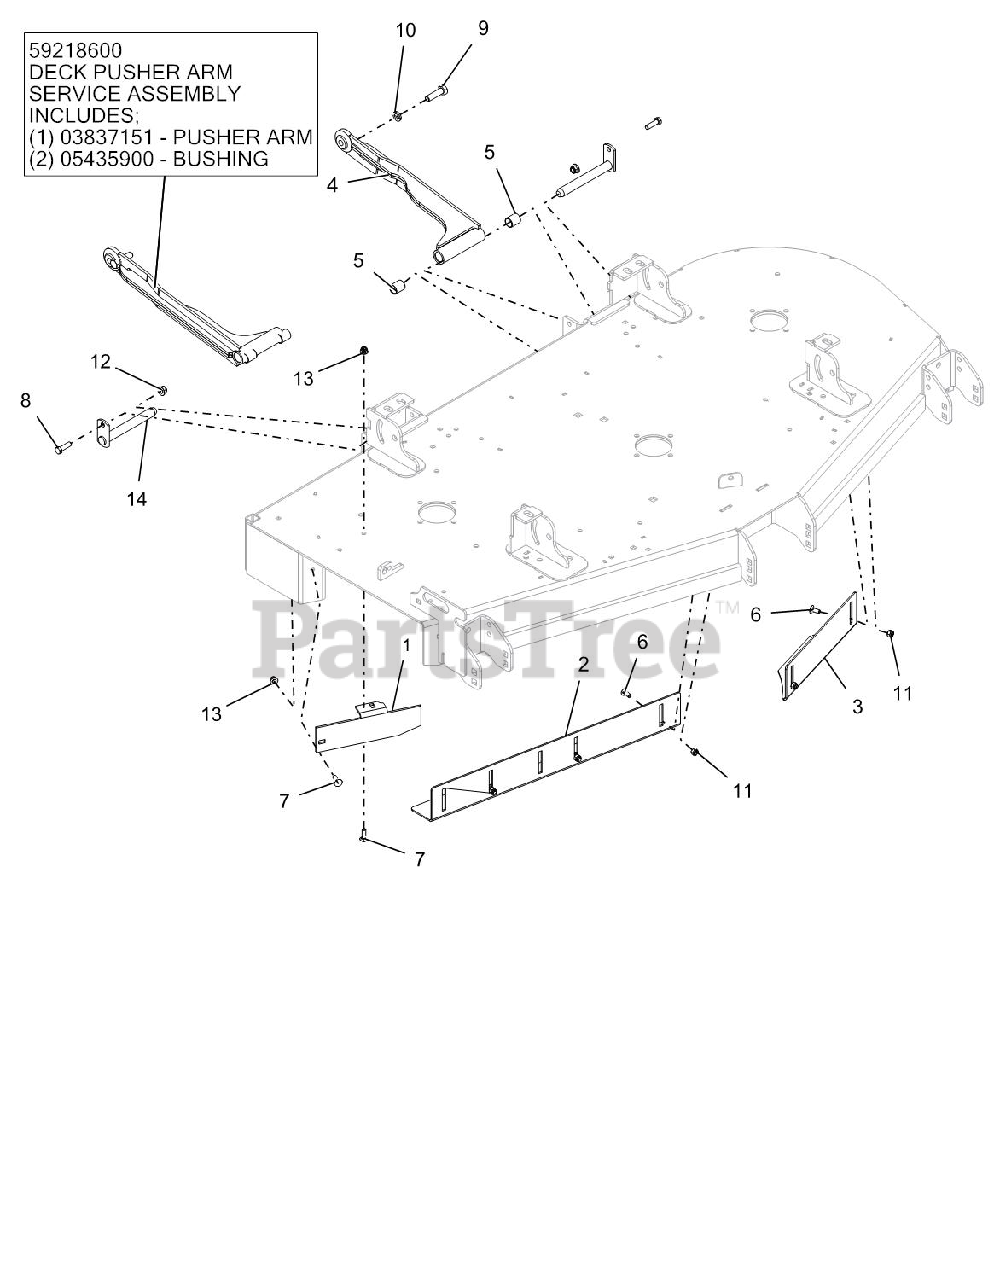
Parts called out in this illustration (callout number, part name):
1	60" DISCHARGE BAFFLE - RED
2	60" RH VACUUM BAFFLE - BLK
3	60" LH VACUUM BAFFLE - BLK
4	BRG, .750 X .875 X 1.000
4	DECK STABILIZER ARM W/BUSHINGS
4	DECK STABILIZER ARM - BLACK
5	BRG, .750 X .875 X 1.000
6	BLT-RDHDSQNK .31-18X.75 G5YZ
7	BLT-RDHDSQNK .31-18X1.00 G5YZ
8	BLT-HEX .38-16X1.25 GR5 YWZC
9	BLT-HEX .50-13X1.75 GR5EP80 YZ
10	WSHR-LK .50X.125 REG YWZC
11	NUT-LK-NYL .312-18 YWZC
12	NUT-LK-NYL-FLG .38-16 YWZC
13	NUT-LK-NYL-FLG .31-18 YWZC
14	WELDMENT, MOWER MTG. PIN
